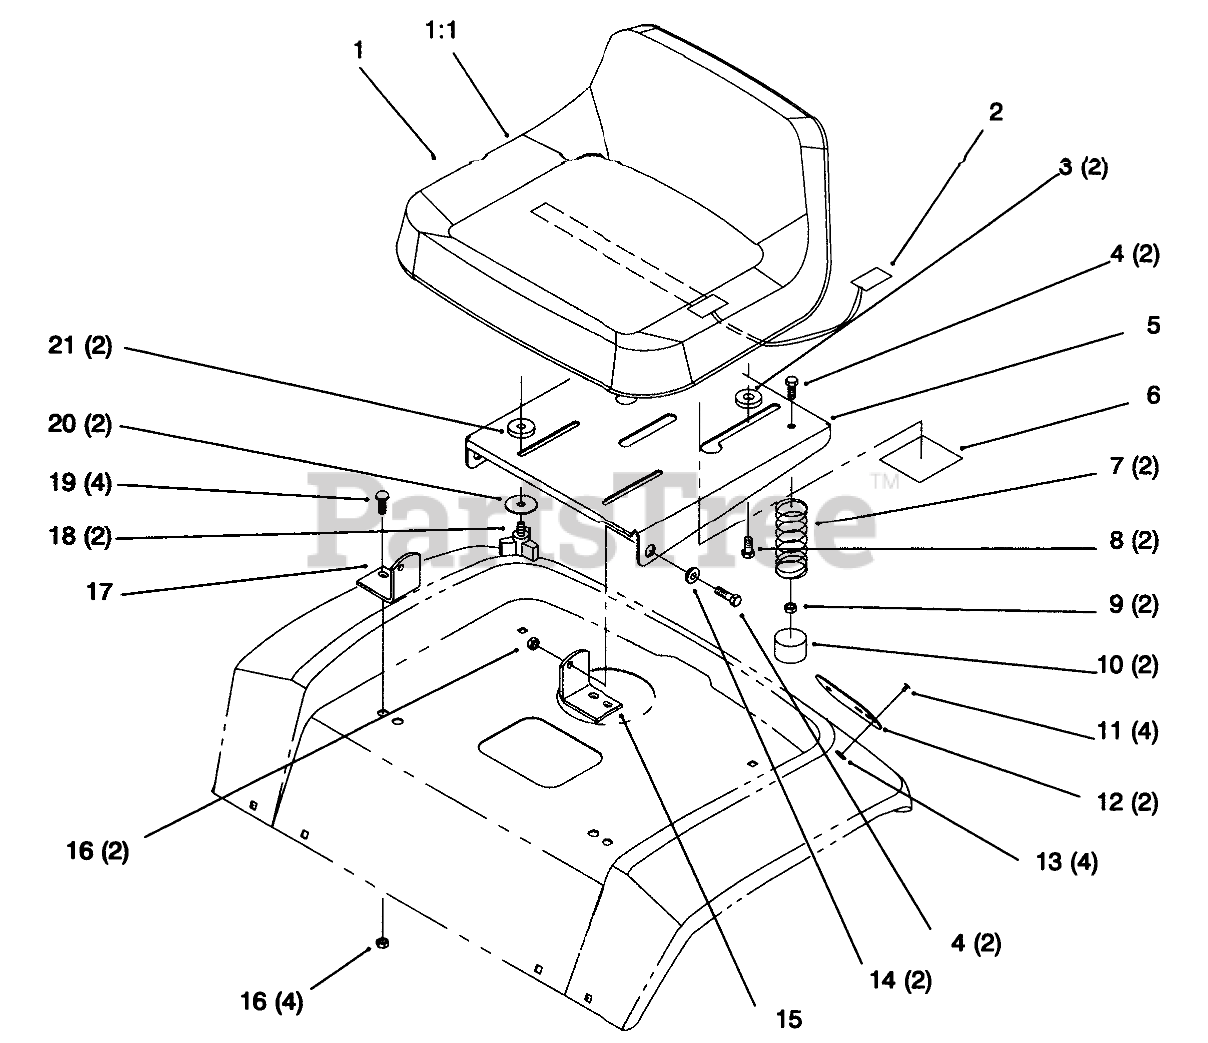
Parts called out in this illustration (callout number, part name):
1	Seat (Only On: 72046)
1	Seat (Only On: 72064)
1:1	Trim-Seat (Service) (Only On: 72064)
2	SWITCH-SEAT
3	SPACER-NYLON
4	SCREW-HH
5	SUPPORT - SEAT (BLACK)
6	Decal-Noise (Only On: 72064)
7	SPRING-COMPRESSION
8	BOLT-SHOULDER
9	NUT-LOCK, NI
10	CAP-PROTECTOR
11	RIVET-BLIND
12	REFLECTOR-STICK ON
13	WASHER-PLAIN
14	BUSHING
15	BRACKET-PIVOT, LH
16	NUT-LOCK, NI
17	BRACKET-PIVOT, RH
19	BOLT-CARR
20	WASHER
21	SPACER-NYLON
